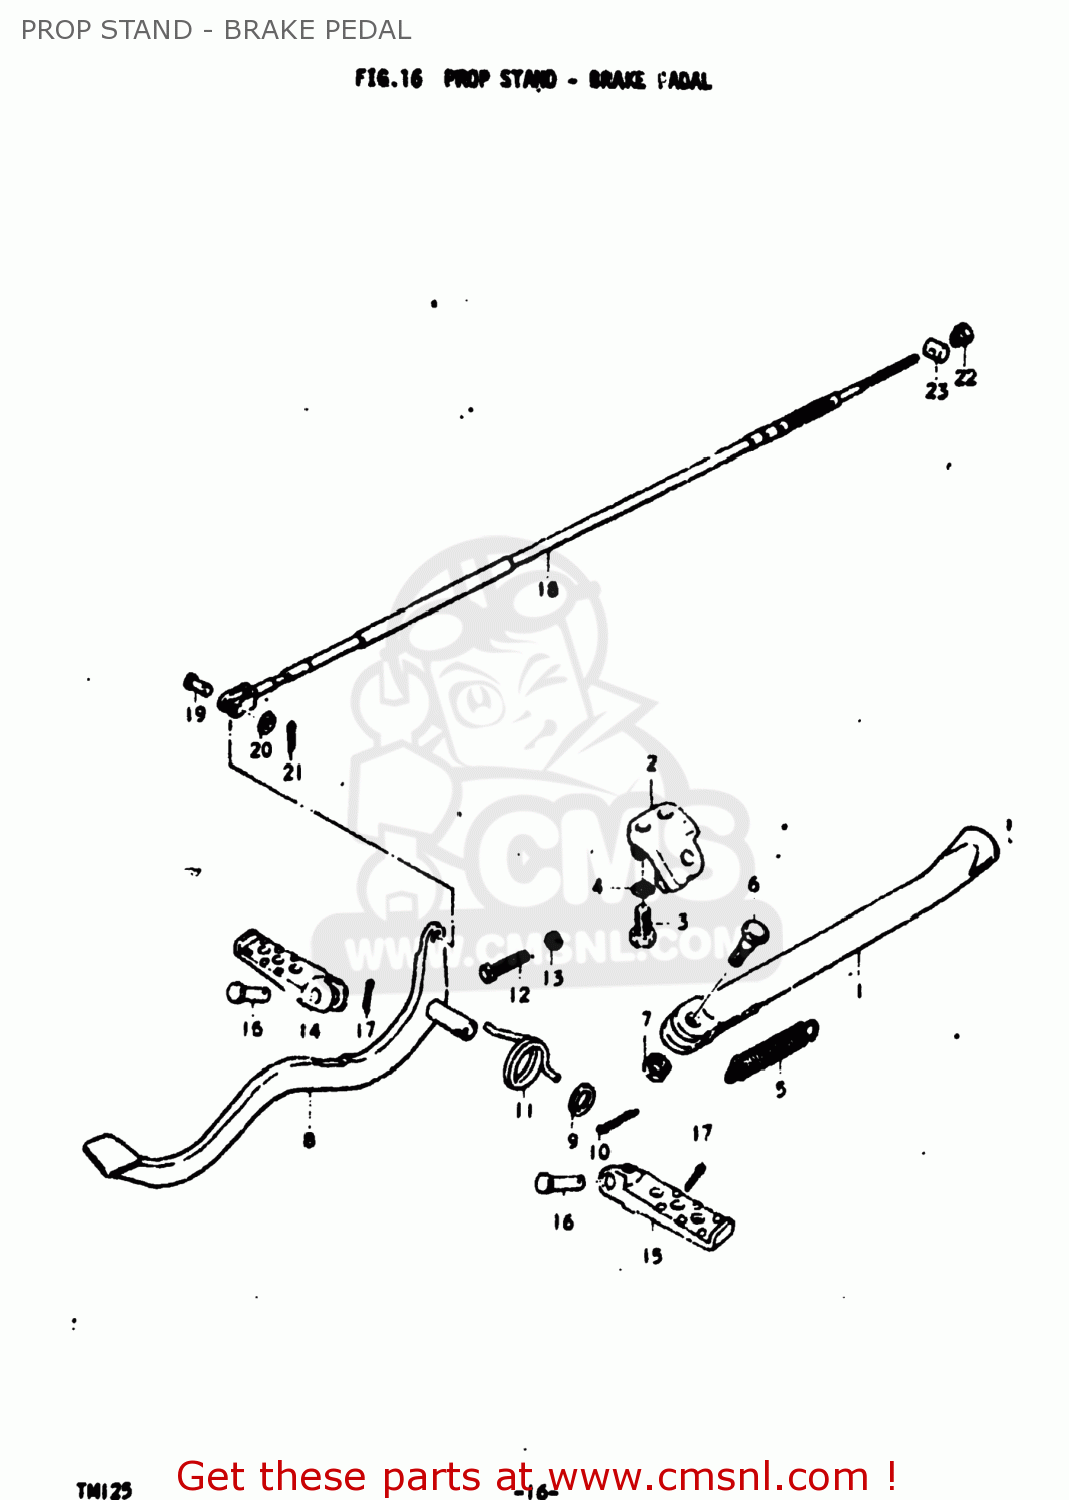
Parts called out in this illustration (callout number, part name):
1	STAND,SIDE
2	BRACKET,SIDE STAND
3	BOLT 10X25
4	LOCK WASHER
5	SPRING
6	BOLT(10X30)
7	NUT
8	PEDAL,BRAKE
9	WASHER
10	PIN 30X20
11	SPRING
12	BOLT
13	NUT
14	BAR,FRONT FOOTREST
15	BAR,FOOTREST,LEFT
17	PIN
18	CABLE,RR BRAKE
19	PIN(L:17.5)
20	WASHER
21	PIN
22	NUT
23	PIN(11X18)
